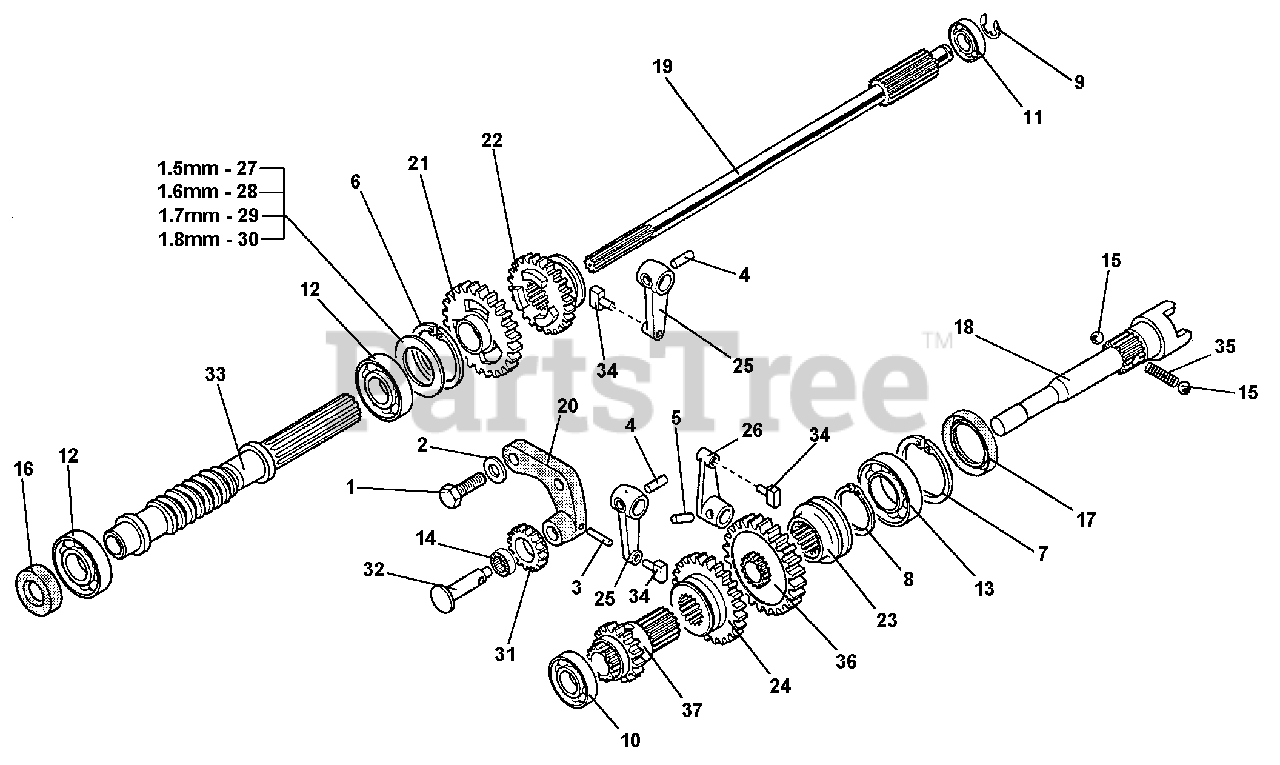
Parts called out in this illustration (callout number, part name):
1	SCREW, M10X30
2	SUPER WASHER 10
3	LOCKING PIN, 4X25
4	LOCKING PIN, 6X24
5	LOCKING PIN, 6X20 SPIRAL
6	CIRCLIP, INTERNAL
7	CIRCLIP, INTERNAL
8	CIRCLIP, EXTERNAL
9	RETAINING RING
10	BEARING, 15X35X11
11	BEARING, 15X42X13
12	BEARING, 25X52X15
13	BEARING, 30X55X13
14	BEARING, 12X15X10
16	OIL SEAL, 15X28X7
17	OIL SEAL, 38X55X7
20	REVERSER BRACKET
22	SLIDER GEAR
24	SLIDER, REVERSER
25	LEVER, SLIDER
26	LEVER, PTO ENGAGMENT
27	SHIM, 1.5MM
28	SHIM, 1.6MM
31	REVERSE GEAR
32	PIN, REVERSE GEAR
35	SPRING, PTO BALLS
